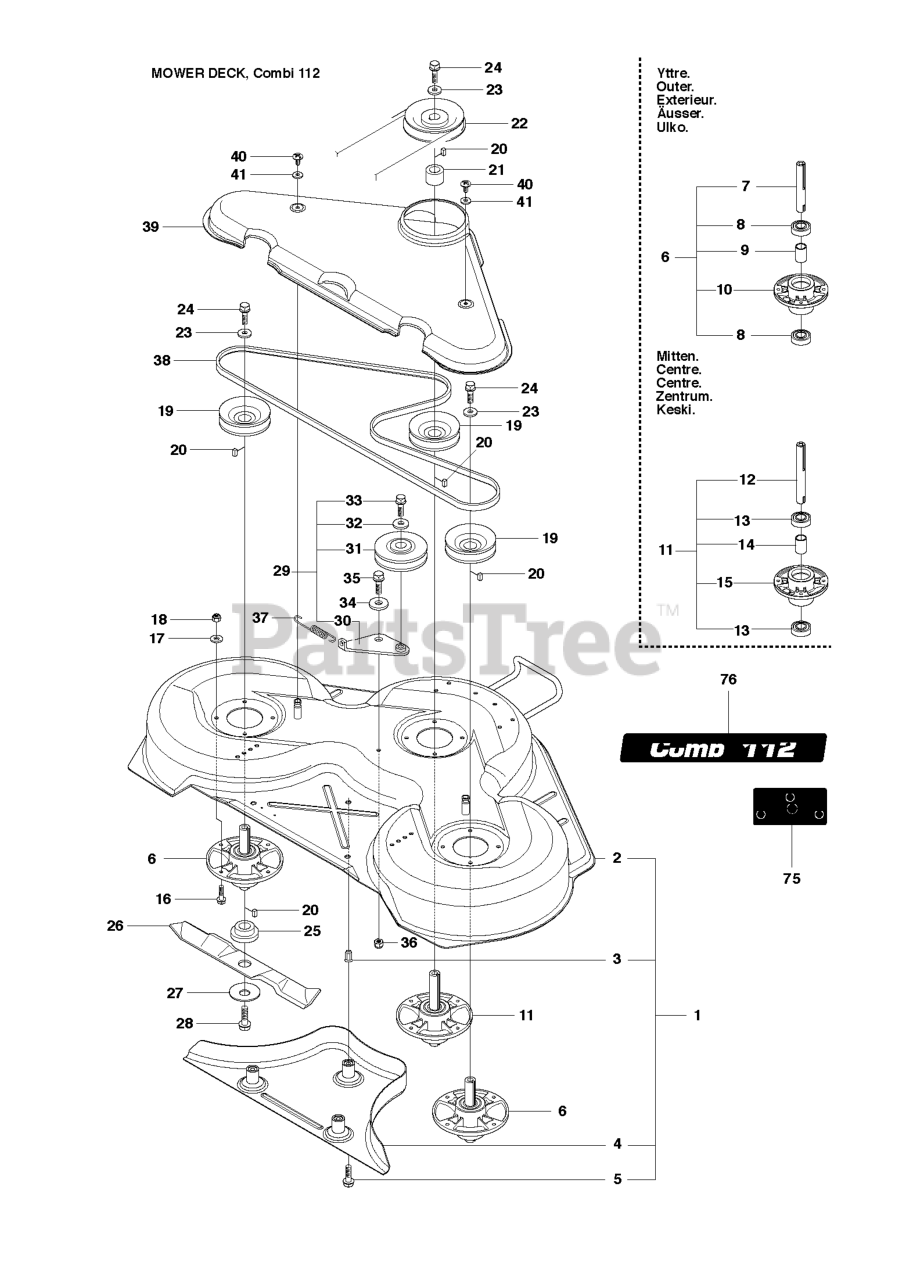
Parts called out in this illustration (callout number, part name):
1	CUTTING DECK C112 GREY RIDER
2	CUTTING DECK ASSY C112 GREY
6	RP SPINDLE ASSY
10	BEARING HOUSING
11	SPINDLE ASSY
15	BEARING HOUSING
17	WASHER BRB 8.4X17
18	LOCKNUT M8
27	WASHER
29	BELT TENSIONER ASSY
30	BELT TENSIONING ARM
34	WASHER
36	LOCKNUT M8
38	BELT
39	BELT COVER
